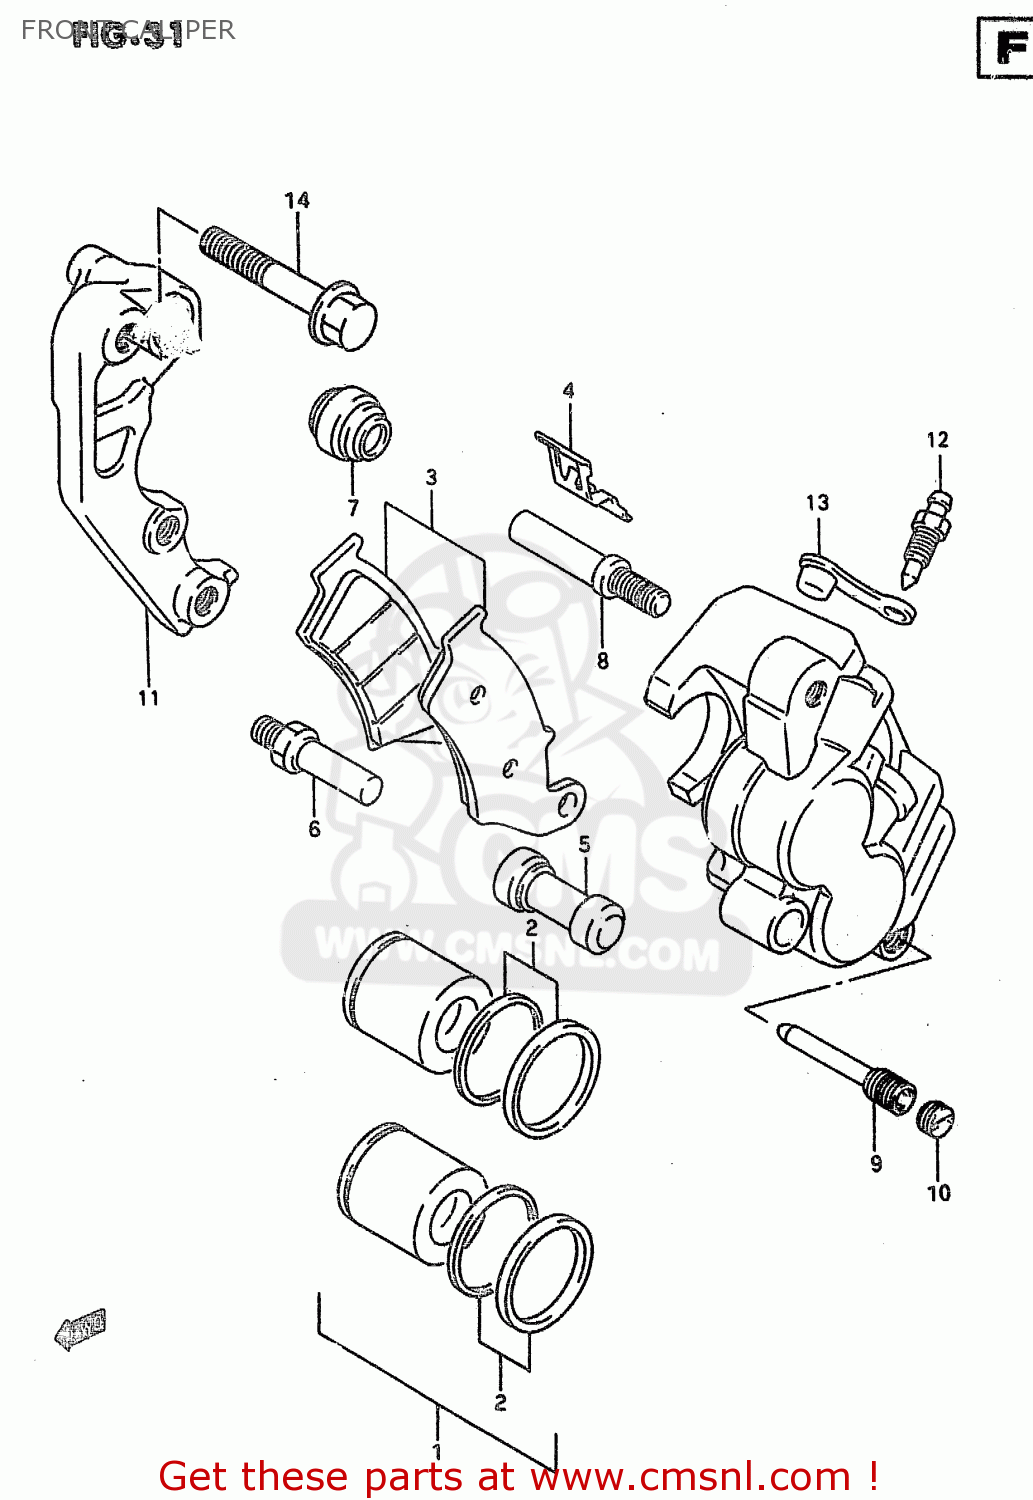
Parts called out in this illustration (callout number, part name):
1	PISTON SET
2	SEAL SET,PISTON
3	PAD SET (NAS)
4	SPRING,PAD
5	BOOT
6	PIN,BOLT
7	BOOT
8	PIN
9	PIN,HANGER
10	PLUG,PIN
11	BRACKET
12	BLEEDER
13	CAP,BLEEDER
14	BOLT(8X40)
